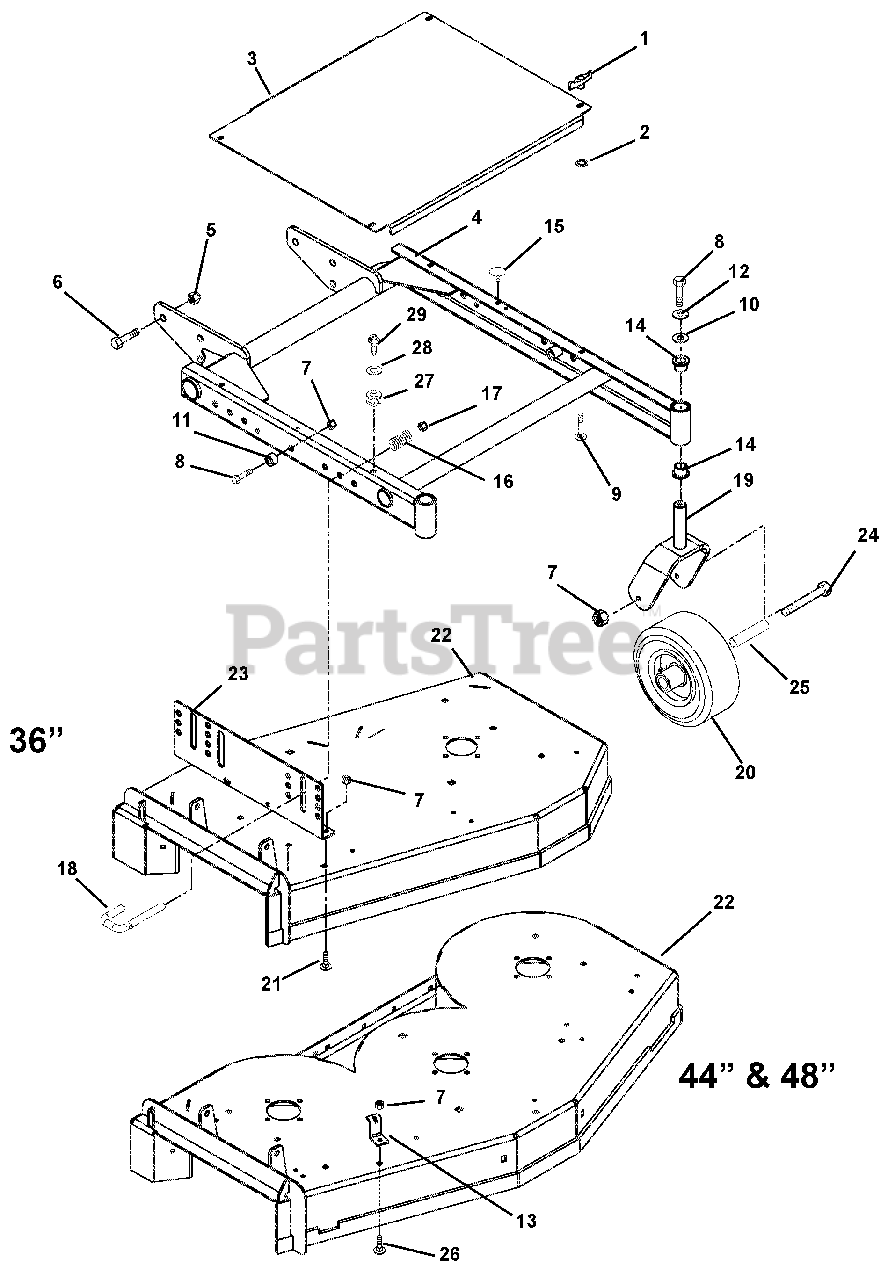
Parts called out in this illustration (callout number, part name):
1	Knob- Wing .312-18 (105, 106, 113, 120)
2	Nut-Push .312 (105, 106, 113, 120)
3	Cover, Belt Pro Mower (105, 120, 312, 314)
4	Weldment - Mower Frame 36" (105, 120, 312, 314)
5	Nut-Locking-Nylon .625-11
6	Bolt-Hex .62-11 x 1.50
7	Nut-Locking-Top-Flange .38-16 (105, 120, 312, 314)
8	Bolt-Hex .38-16 x 1.25 Grade 5
9	Bolt-Round Head Square Neck .31-18 x 1.00 (105, 106, 113, 120)
10	Washer-Flat-Steel .38 x 1.50 x .125
11	Bushing
12	Washer-Locking .38 x .094 Regular
13	Anchor, Spring (106, 113)
14	Bushing-Flange 1.00 x 1.25 x 1.50 x 1.50
15	Bumper Grommet .125 x .25 Dia.
16	Spring-Compression .058 x .65 x 2.13
17	Nut-Locking-Center .50-13
18	Pin- Latch
19	Weldment-Caster Fork
20	Wheel 9 x 3.50
21	Bolt-Round Head Square Neck .38-16 x 1.00 Grade 5
22	Kit, 36" Fixed Mower Deck with Decals (105, 120, 312, 314)
23	Kit-Mower Side Support Bracket-Right Hand and Left Hand
24	Bolt-Hex .38-16 x 5.50
25	Bearing .625 x .380 x 4.08
26	Bolt-Round Head Square Neck .38-16 x .75 Grade 5
27	Grommet, Plastic (312, 314)
28	Washer-Flat-Steel .281 x .62 x .065 (312, 314)
29	Screw-Tapping .25-20 x .50 Hex Washer Head (312, 314)
